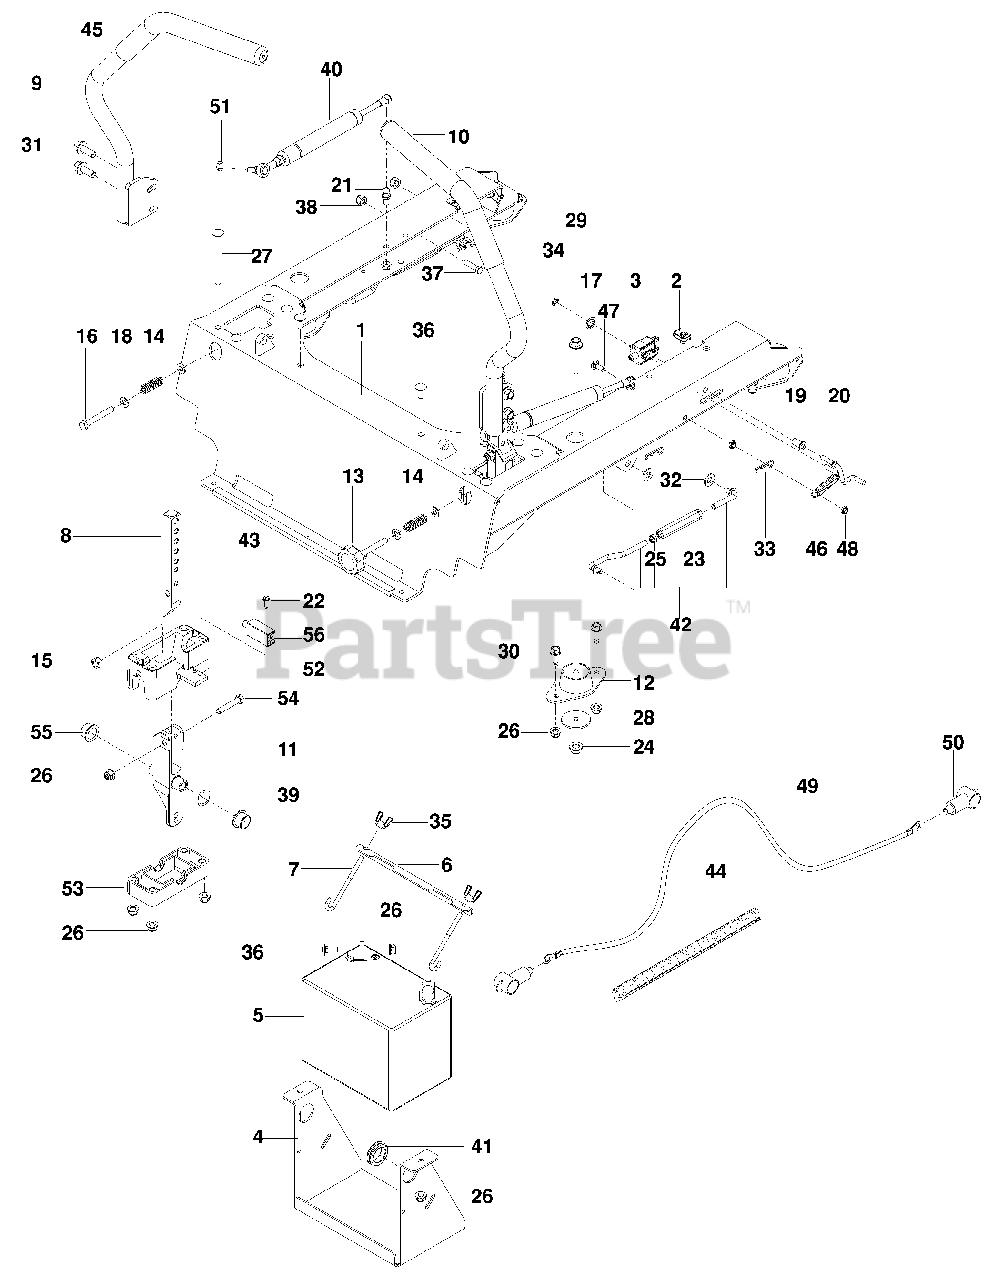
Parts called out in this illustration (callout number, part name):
1	FRAME MOUNT
2	RETAINER, U TYPE
3	SWITCH, BRAKE (3-POLE)
4	BRACKET, BATTERY
5	BATTERY
6	BRACKET, BATTERY MOUNT
7	J HOOK
8	LEVER, MOTION
9	LEVER, w/ GRIP, RT
10	LEVER, w/ GRIP, LT
11	LEVER, CONTROL
12	MOUNT, ISO
13	KNOB
15	NUT 5/16-18 HEX
16	BOLT 5/16-18 x 2½ HEX TPBLT
17	RETAINER NUT 3/8
18	WASHER 5/16 SAE FLAT
19	BUSHING, ¼ FLANGE
20	LINK, SWITCH
21	BALL STUD 10MM
22	SCREW 10-24 x 5/8 WSH HD
23	TURNBUCKLE 3/8
24	NUT 3/8-16 HEX FLG NYLOC
25	NUT 3/8-24 HEX JAM
26	NUT 5/16-18 HEX FLG NYLOC
27	BOLT 5/16-18 x 3 ¾ RD HD
28	WASHER 3/8 SPECIAL
29	SCREW 3/8-16 x 2 HEX FLG
30	SCREW 5/16-18 x ¾ HEX FLG
31	SCREW 3/8-16 x 1 HEX FLG
32	WASHER 3/8 SAE FLT
33	HAIRPIN COTTER
34	PUSH NUT, ¼"
35	WINGNUT ¼-20 NYLOC
36	BOLT 5/16-18 x ¾ RD HD
37	BOLT 10-24 x ¾ SOCKET HD
38	NUT 10-24 HEX NYLOC
39	WASHER, WAVE
40	DAMPENER ASSY
41	RUBBER GROMMET
42	SEAT STRUT ASSY
43	FLEX TRIM
44	LOOM, SPLIT, 5/8
45	GRIP, LEVER
46	SPRING
47	BOLT ¼-20 x ¾ GR2 RD HD
48	NUT ¼-20 HEX THIN NYLOC
49	CABLE, POSITIVE
51	WASHER 5/16 SLW
52	BLOCK, UPPER
53	BLOCK, LOWER
54	BOLT 5/16-18 x 1¾ HEX NYL
55	BEARING, FLANGE
56	SWITCH N.C.
